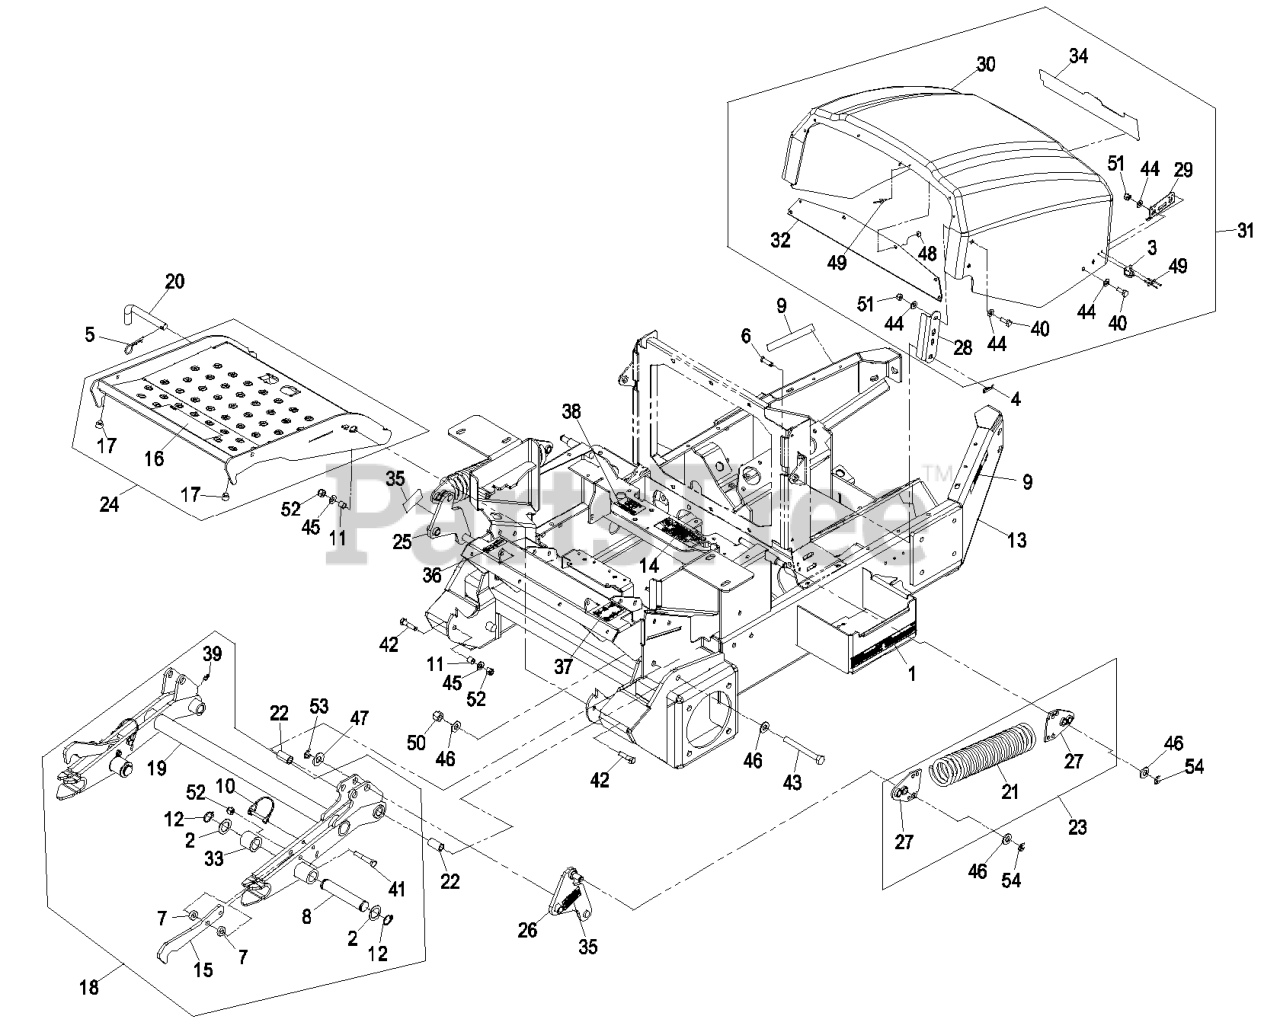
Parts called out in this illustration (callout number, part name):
1	DECAL-BATTERY
2	WASHER-SPACER
4	PIN-COTTER
5	PIN-COTTER
6	PIN-CLEVIS
7	SPACER
9	DECAL-WARNING
10	PIN-HITCH
11	SPACER-TUBE, PUMP LINK
12	RING-RETAINING
13	ASM,FMZ DIESEL FRM W/DECA
14	DECAL,PUMP FAN WARNING
15	LATCH, FMZ HITCH (PLATED)
16	DECAL-WARNING
17	BUMPER-RUBBER
18	ASM,HITCH FMZ
20	PIN,FULL FOLD (PLTD)
21	SPRING,EXTENSION (PLATED)
22	BUSHING,HITCH PIVOT
23	ASM,FMZ WT XFR SPRING
25	ASM,FMZ RH SPRING BELLCRA
26	ASM,FMZ LH SPRING BELLCRA
27	WLD,FMZ SPRING ANCHOR (PL
28	BRACKET, HOOD PIVOT
29	HOOK, HOOD
31	ASM,FMZ LC HOOD W/DCL COM
32	SCREEN,HOOD
33	ROLLER,LOCK LEVER
34	DECAL,FRONTRUNNER
35	DECAL,SPRING LOADED
36	DECAL-CONTROL, MOTION
37	DECAL,MOTION CNTL/PARK BR
38	DECAL,PUMP DRIVE RELEASE
39	FITTING-GREASE
40	SCREW-HH
41	SCREW-HH
42	SCREW-HH
43	SCREW-HH
44	WASHER-PLAIN
45	WASHER-FLAT
46	WASHER-FLAT
47	WASHER-FLAT
48	WASHER-BACK
50	NUT-LOCK, NI
51	NUT-LOCK, NI
52	NUT-LOCK, NI
54	RING-RETAINING, EXTERNAL
